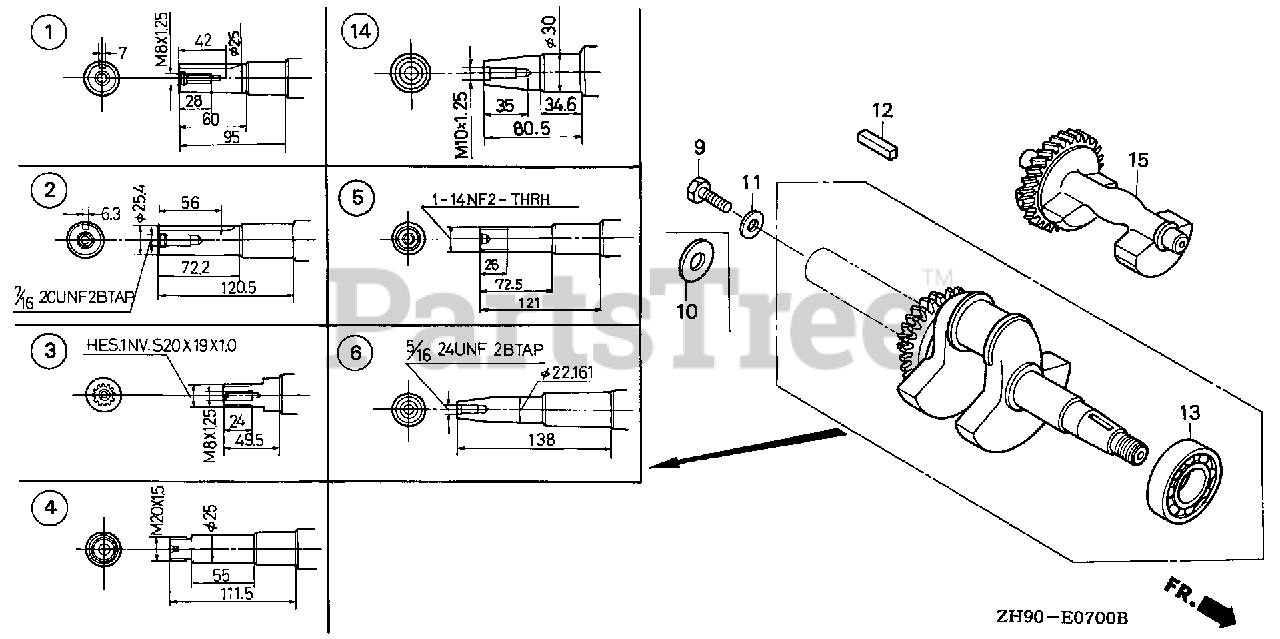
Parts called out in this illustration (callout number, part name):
2	CRANKSHAFT
12	KEY (6.3X6.3X43)
13	BEARING, RADIAL BALL (6206 SH)
